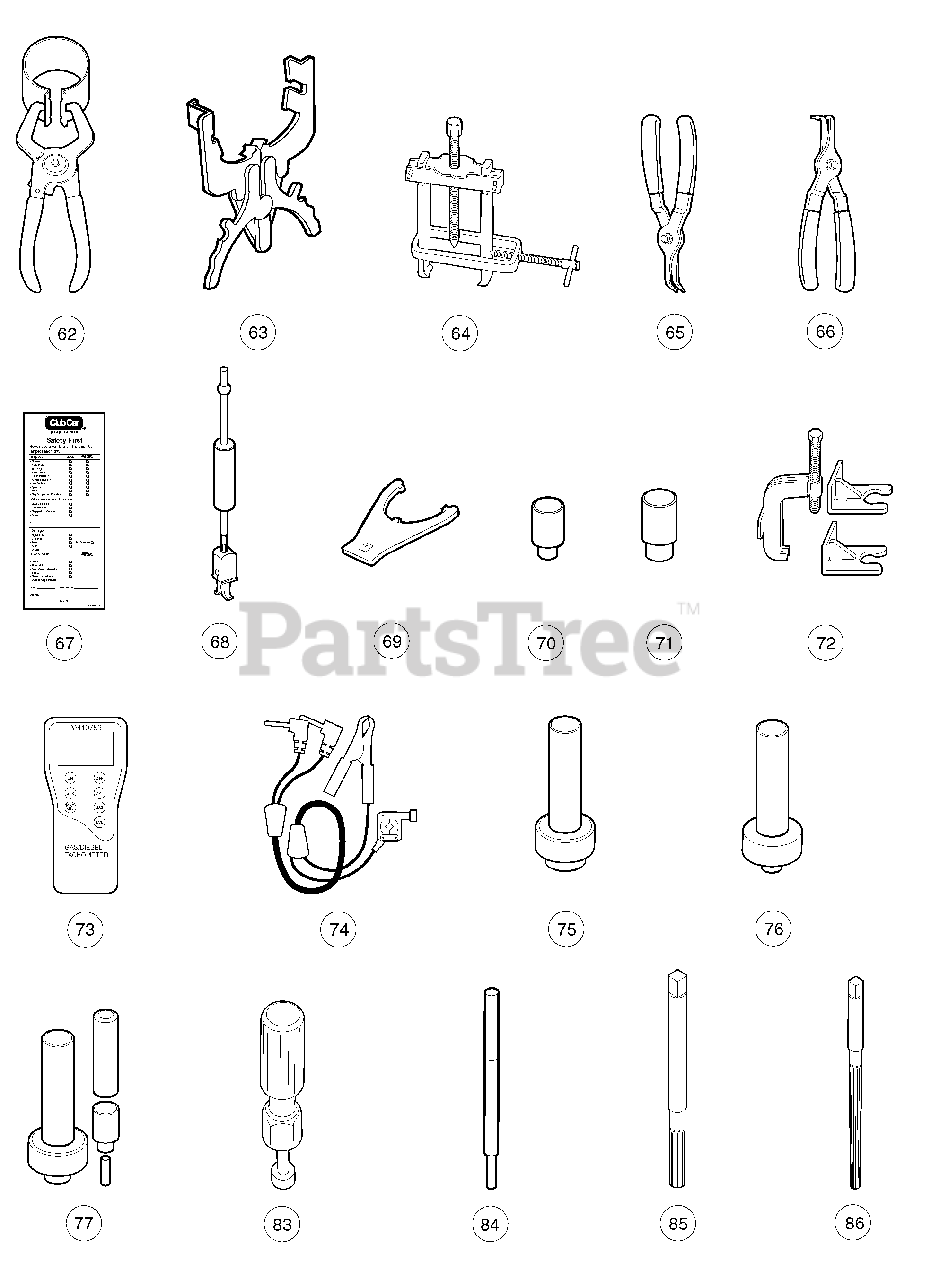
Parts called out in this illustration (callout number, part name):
62	Piston Ring Compressor Kit (FE290, FE350 and FE400 engines)
63	Piston Ring Pliers (for Kawasaki Engines)
64	Puller, Special Use (for Kubota D722 Diesel Engines)
65	Retaining Ring Pliers, 45deg External
66	Retaining Ring Pliers, 90deg Internal
67	Safety First Card (50 per pack)
68	Seal Puller
69	Spanner Wrench
70	Steering Column Bearing Press Tool
71	Steering Column Retaining Ring Tool
72	Steering Wheel Puller Tool
73	Tachometer
74	Tachometer Diesel Probe (for use with item 73)
75	Transaxle Axle Seal Tool
76	Transaxle Pinion Seal Tool
77	Transmission Tool Kit
83	Valve Clearance Adjuster Screw Holder (for FE290 engines only)
84	Valve Guide Driver (for Honda GX620 Gasoline Engines)
85	Valve Guide Reamer (FE290, FE350, and FE400 only)
86	Valve Guide Reamer, 6.6 mm (for Honda GX620 Gasoline Engines)
